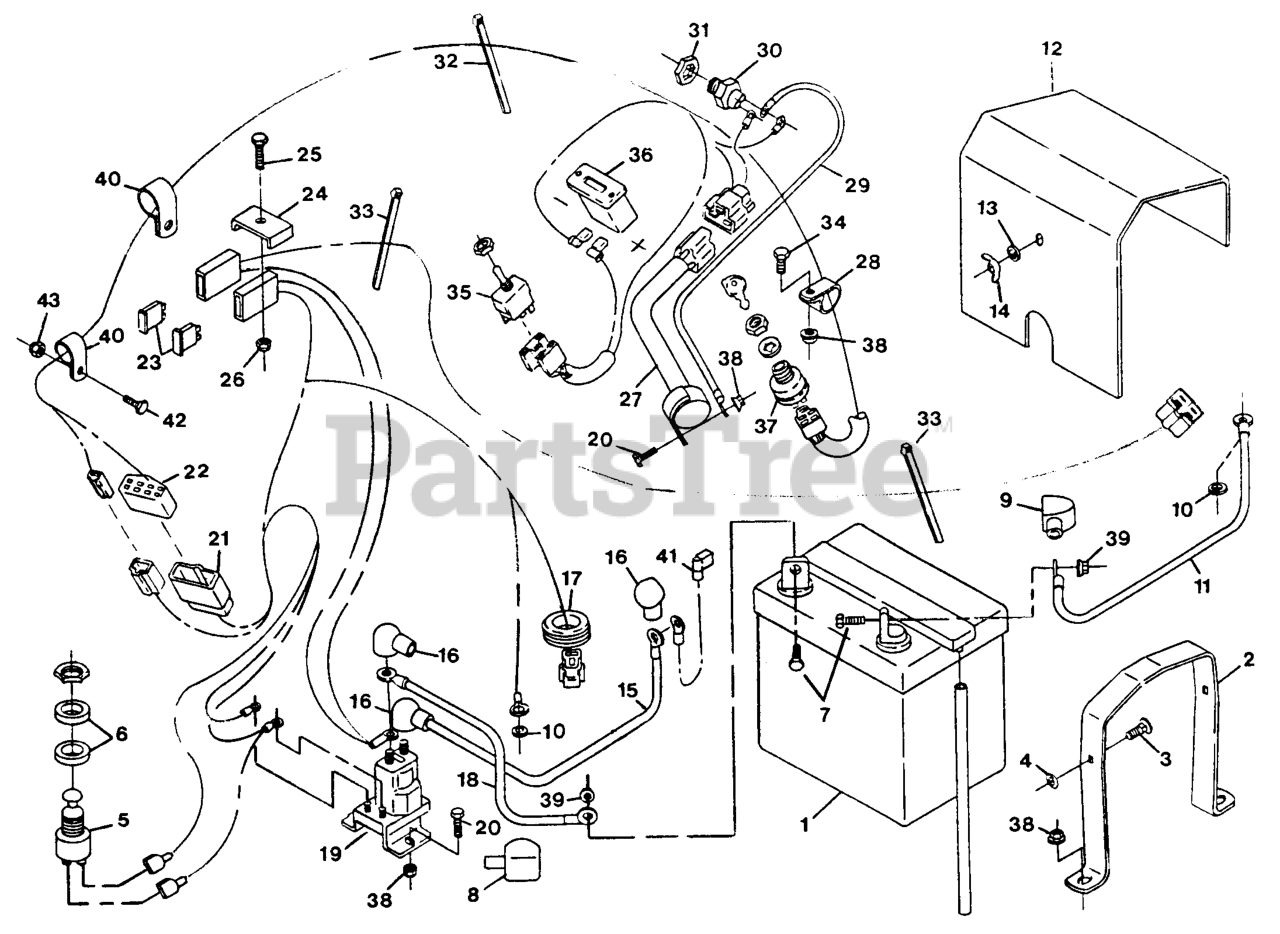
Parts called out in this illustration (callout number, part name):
1	Battery, 12v Manifold
2	STRAP,BATTERY HOLDDOWN
3	BOLT-CARR
4	NUT-RETAINING
5	SWITCH,PUSH BUTTON
9	INSULATOR, BATTERY -
11	WIRE-GROUND
14	NUT-WING
16	INSULATOR-SOLENOID
17	GROMMET
21	HARNESS,WIRING HYDRO
23	FUSE-BLADE TYPE, 20 AMP
24	CLIP-FUSE BLOCK PLTD
28	CLIP-LOOM
30	SWITCH,OPERATOR CNTRL
32	TIE-PLASTIC
33	TIE-CABLE
35	SWITCH,W/TERM CLIPPD
36	METER-HOUR
37	SWITCH,IGNITION
40	CLIP-LOOM
